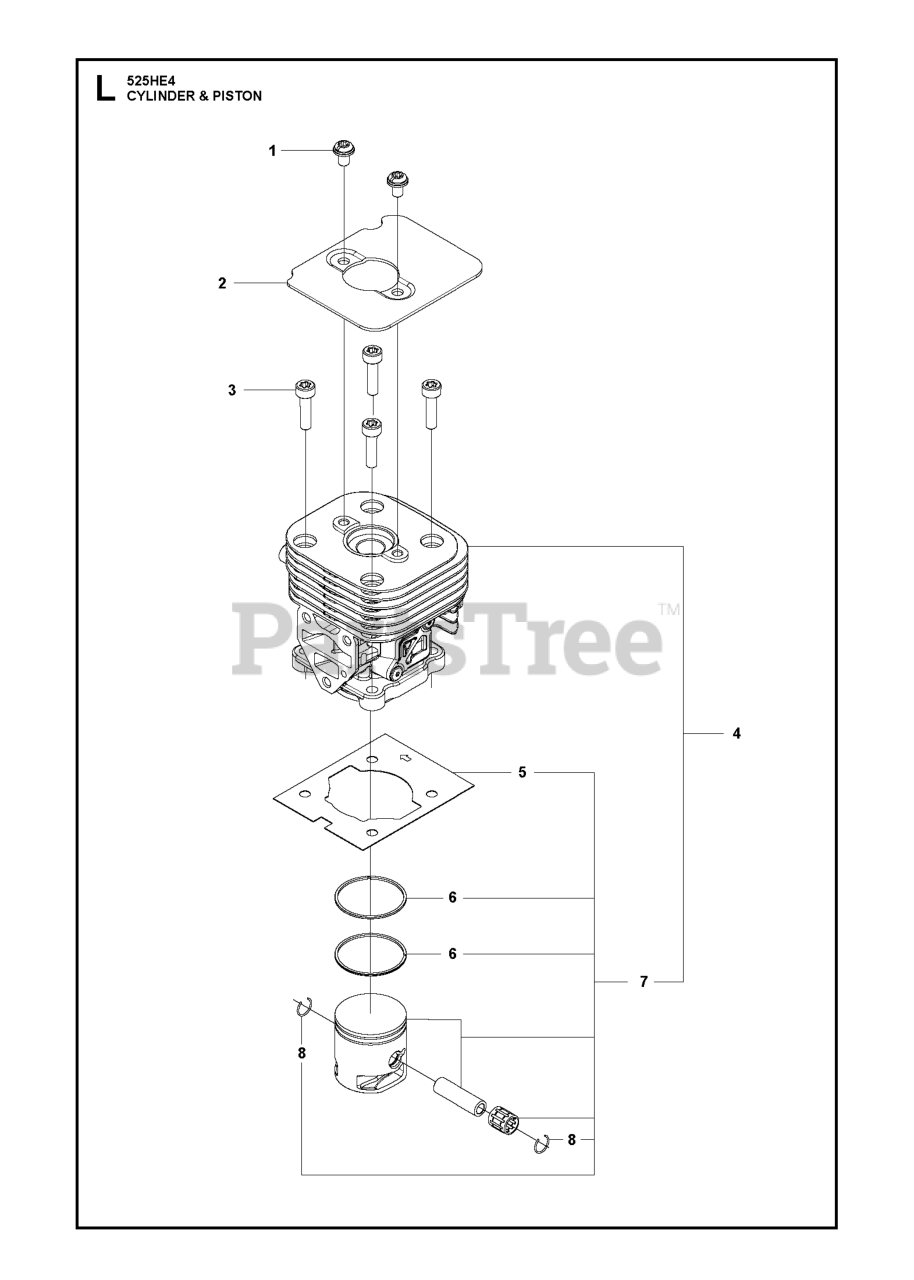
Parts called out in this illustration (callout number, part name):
2	PLATE CYLINDER
3	BOLT
4	SERVICE KIT
5	GASKET BASE
7	SERVICE KIT PISTON 525 TRIMMER
